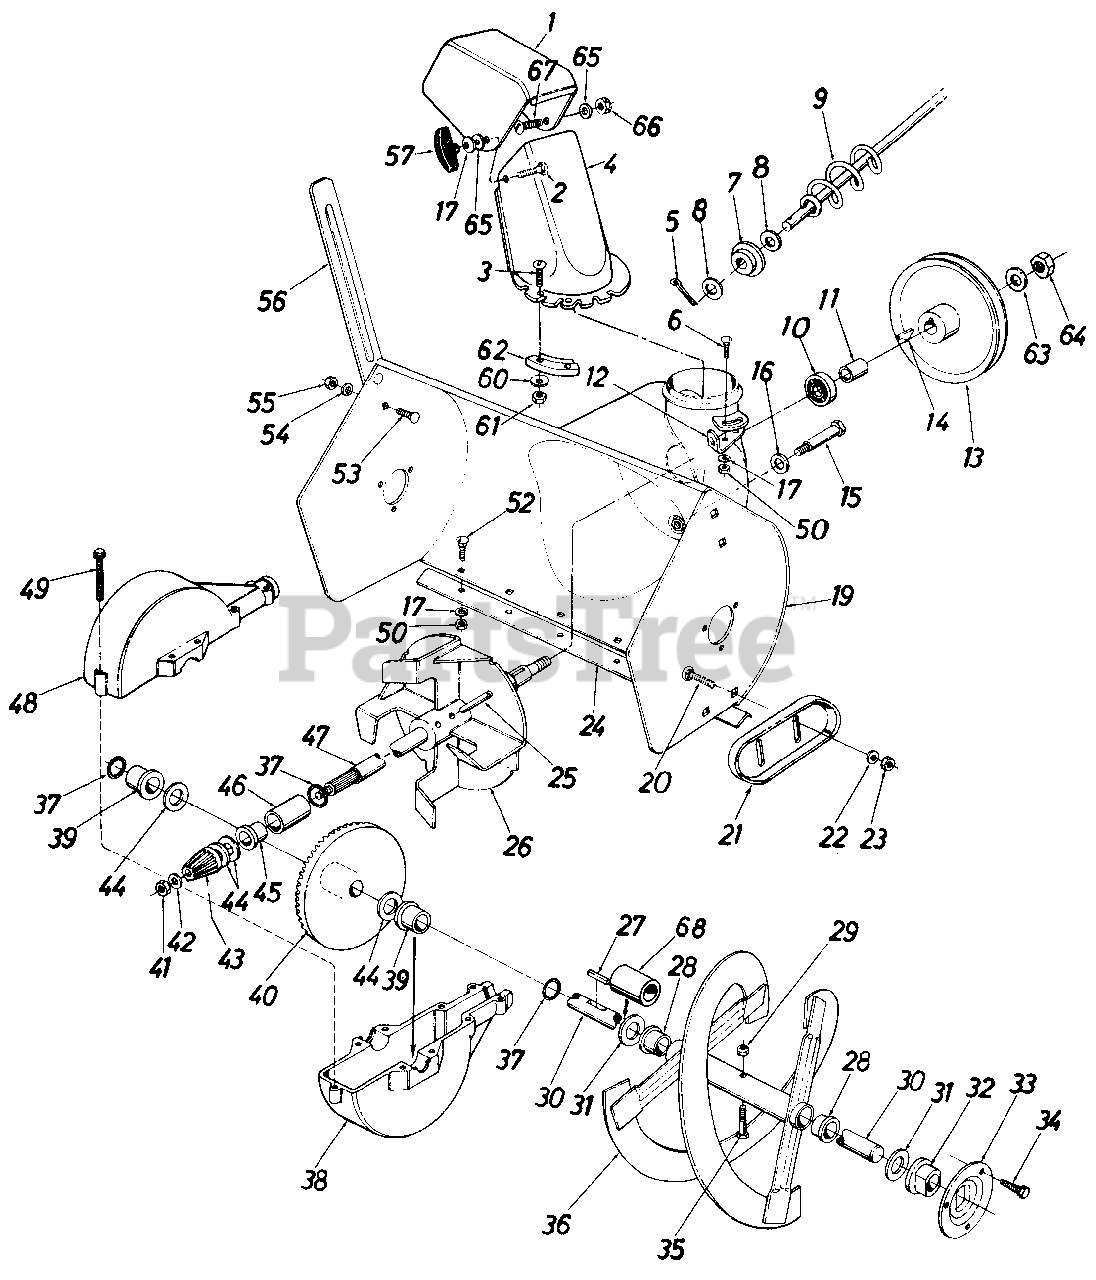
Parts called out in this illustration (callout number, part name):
1	Upper Chute
2	Carriage Bolt 5/16-18 x 1.0"*
3	Truss Mach. Scr. 1/4-20 x .75"
4	Lower Chute
5	Coter Pin
6	Carriage Bolt 5/16-18 x .75"*
7	Bushing
8	Fl-Wash. .385 I.D. x .62" O.D.
9	Chute Crank Ass'y.
10	Ball Brg 621 I.D. x 1.38" O D
11	Spacer .63" I.D. x .88" O.D. x .900" Lg.
13	1/2" "V"-Pulley .625" I.D. x 7.50" O.D.
14	#61 Hi-Pro Key 3/16" x .518" Dia.
15	Shld. Bolt .50" Dia. x 2.11"
16	Bell-Wash. .40" I.D. x .88" O.D. x .06
17	Bell-Wash. .34" I.D. x .88" O.D.
20	Carriage Bolt 3/8-16 x .62'
21	Slide Shoe
22	Bell-Wash. 3/8" I.D.
23	Hex Jam Nut 3/8-16 Thd.
24	20" Shave Plate
26	11" Dia. Blower Fan Ass'y.
27	Sq. Key 3/16" x 1.5" Lg.
28	Flange Brg. .75" I.D. x .88" O.D.
29	Hex Ins. L-Nut 5/16-18
30	Spiral Axle
31	Fl-Wash. .75" I.D. x 1.50" O.D. x .06
32	Flange Brg. w/Flats .755" I.D.
33	Bearing Housing
34	Hex Wash. Hd. Self-Tap Scr. 5/16-24 x .62" Lg.
35	Hex Bolt 5/16-18 x 1.50" Lg.
36	20" Spiral Ass'y.L.H.
37	"O"-Ring-3/4" I.D.
38	Bevel Gear Housing-Lower Half
39	Plastic Flange Brg. .755" I.D.
40	Bevel Gear
41	Hex Cent. L-Nut 5/16-24 Thd.
42	Fl-Wash. .34" I.D. x .62" O.D. x .06
43	Pinion Gear
44	Fl-Wash. .75" I.D. x 1.25" O.D. x .06
45	Flange Brg. .755" I.D.
46	Sleeve Brg. .755" I.D.
47	Blower Axle
48	Bevel Gear Housing- Upper Half
49	Hex Wash. Hd. Self-Tap Scr. 1/4 -20 x 1.00" Lg.
50	Hex Nut 5/16-18 Thd.*
52	Carriage Bolt 5/16-18 x .62"
53	Carriage Bolt 5/16-18 x .62" Lg.*
54	L-Wash. 5/16" I.D.*
55	Hex Nut 5/16-18 Thd.*
56	Drift Cuter Bar
57	Knob
60	Fl-Wash. 1/4" I.D.
61	Hex L-Nut 1/4-20 Thd.*
62	Chute Flange Keeper
63	Fl-Wash. .64" I.D. x .94" O.D. x .06
64	Hex Jam Nut 5/8-18 Thd.
65	Fl-Wash. .344 I.D. x 1.125
66	Hex L-Nut 5/16-18 Thd.
67	Truss Mach. Scr. 5/16-18 x .75" Lg.*
68	Spacer
